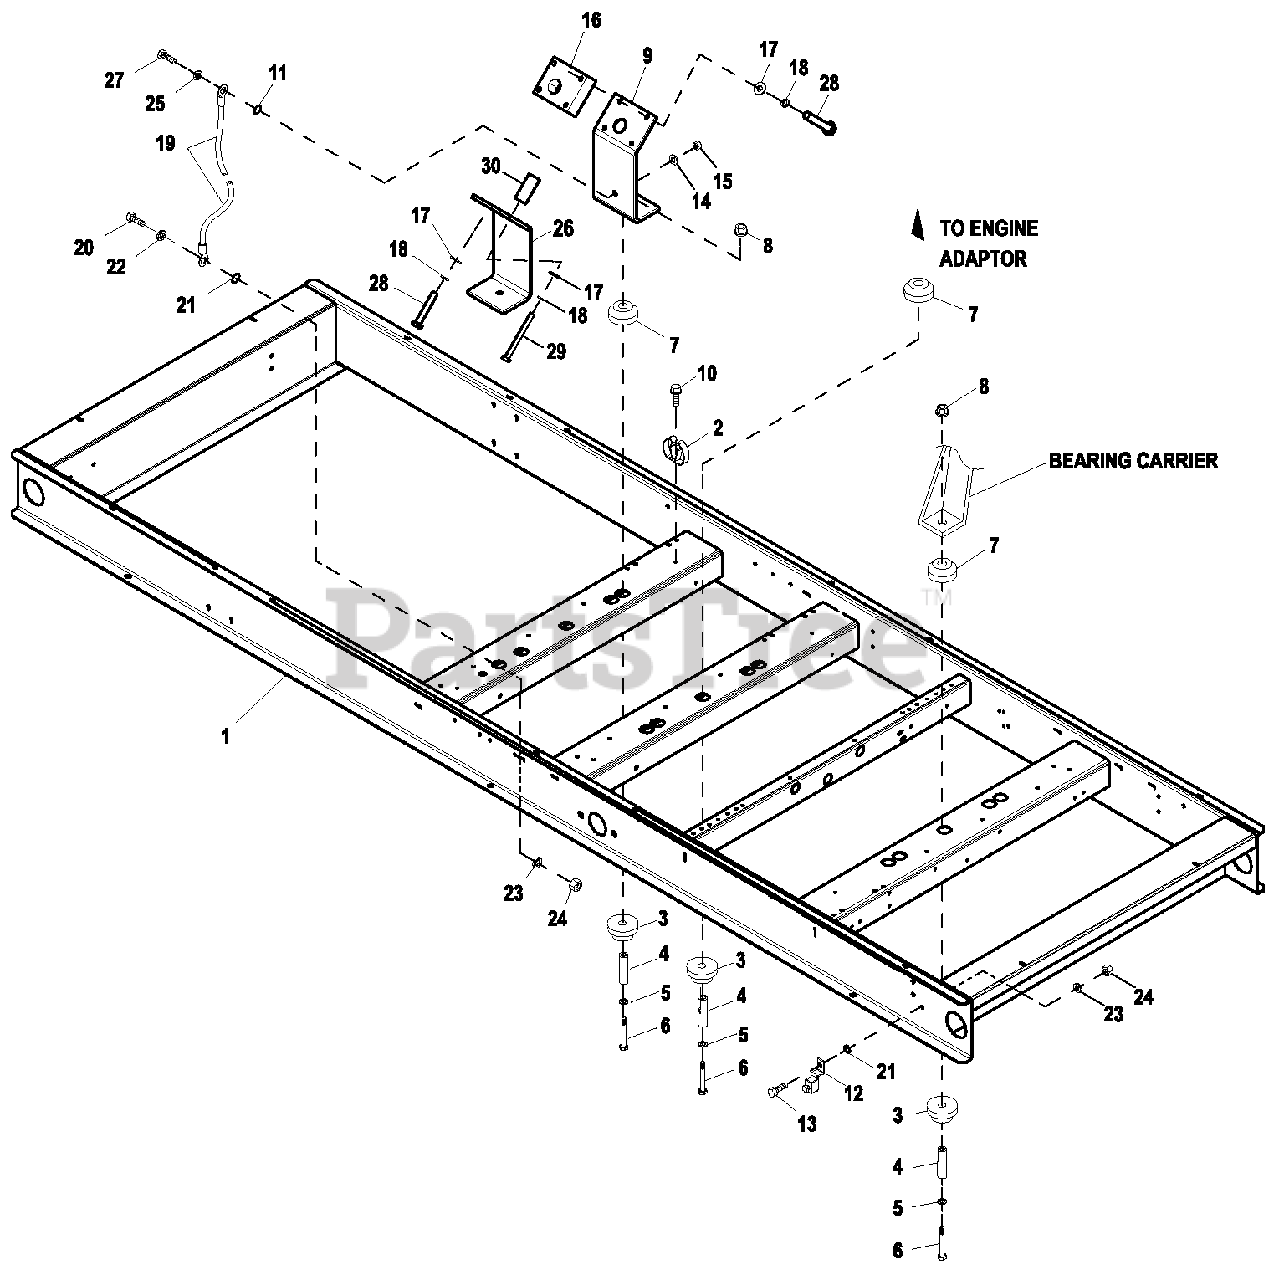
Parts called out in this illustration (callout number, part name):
1	MTG BASE C5 150KW
2	SPRING CLIP HOLDER .37- 62
3	DAMPENER VIBRATION
4	SPACER .49 X .62 X 1.87 PWDR/ZINC
5	WASHER FLAT M12
6	SCREW HHC M12-1.75X85 G8.8
7	DAMPENER VIBRATION 50 WHITE
8	NUT LOCKING M12-1.75
9	ENGINE SUPPORT 6.8LRH
10	SCREW HHTTM4-0.7X8BP
11	WASHER SHAKEPROOF INT 1/4
12	LUG SOLDERLESS 3/0-#4 X 13/32 CU
13	SCREW HHC M8-1.25X25 G8.8
14	WASHER FLAT 1/4-M6 ZINC
15	NUT HEX M 6X1.0 G8 YELCHR
16	5.4L RH ENGINE MOUNT SPACER
17	WASHER FLAT 3/8-M10ZINC
18	WASHER LOCK M10
19	ASSY WIRE 14.00"
20	SCREW HHC M8-1.25X30 G8.8
21	WASHER SHAKEPROOF INT 3/8
22	WASHER LOCK M8-5/16
23	WASHER FLAT 5/16-M8ZINC
24	NUT HEXM8-1.25G8 YELCHR
25	WASHER LOCK M6-1/4
26	ENGINE MOUNT 6.8LLH SIDE
27	SCREW HHC M6-1.0X30 G8.8
28	SCREW HHC M10-1.5X60 C8.8
29	SCREW HHC M10-1.5X70 C8.8
30	SPACER .41 X .7 5 X 1 .6 8 ST/ZNC
